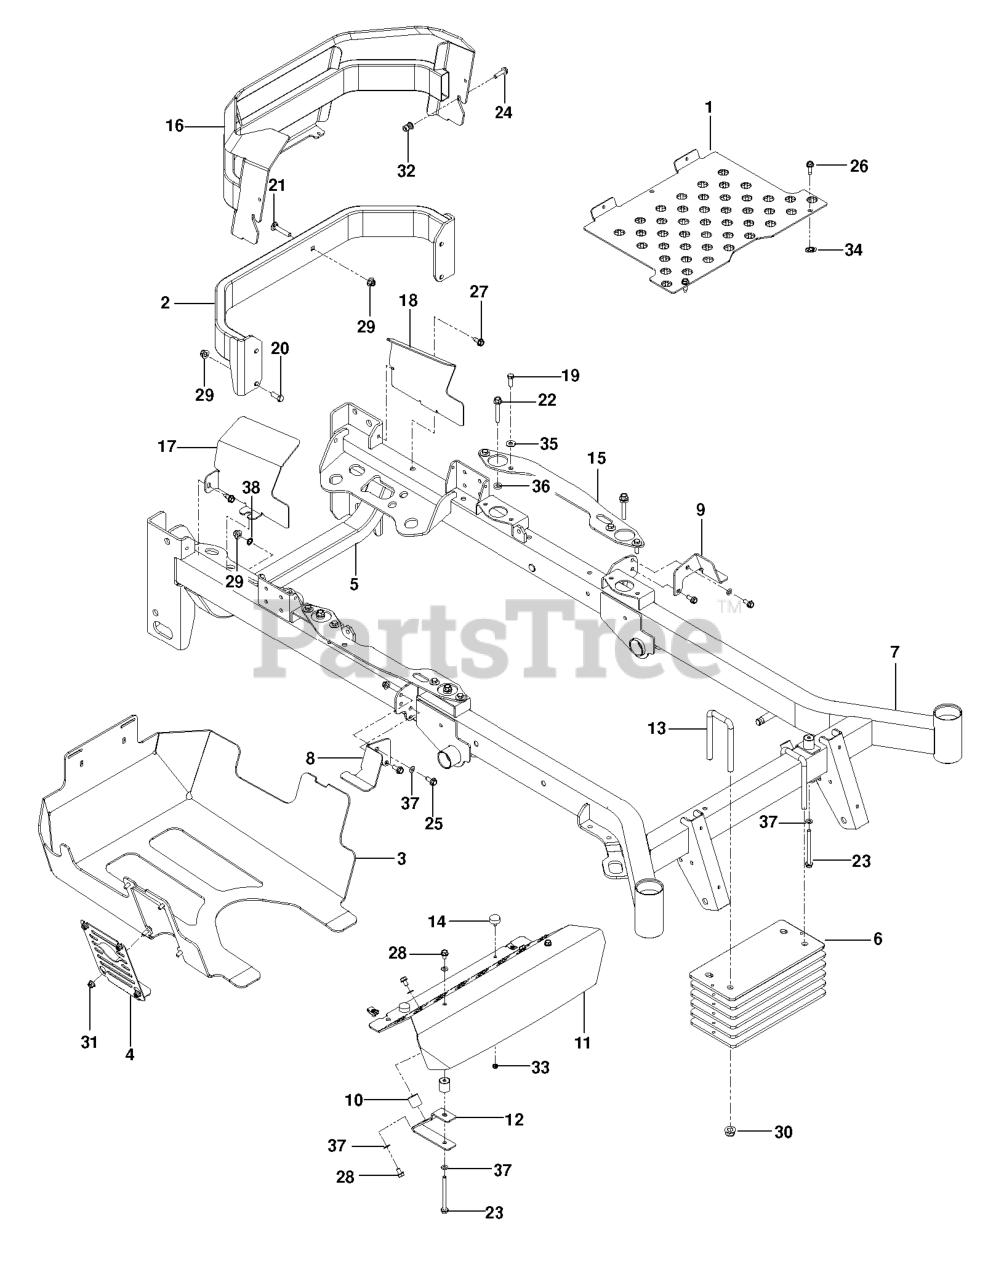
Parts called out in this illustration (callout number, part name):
1	PLATE, FLOOR PAN, OR
2	BUMPER, REAR, ORG
3	SKID.PLATE.GRAY
4	PANEL.ACCESS.GRAY
5	CROSS MEMBER, GRAY
6	PLATE, WEIGHT BLK
7	FRAME.W/DECALS.PZ6029/PZ29
8	XX MOUNT, TANK, RT-BLK
9	MOUNT, TANK, LT-BLK
10	MOUNT, F/F INSERT
11	PLATE, FOOT REST, OR
12	BRACKET, REST MOUNT
13	LINKAGE, U-BOLT
14	GROMMET, BUMPER
15	SKIRT.RH.BLK
16	GUARD, REAR W/DECALS
18	GUARD.LT.REAR.GRAY
19	HCS 5/16C X 1
20	HCS 3/8-16X1.GRD.5.ZD
21	RHSNB 3/8C X 2
22	HHFS 3/8-16 X 2-1/4 GR 5 ZD
23	HHFS 5/16-18 X 3 3/4
24	HHFS 5/16-18 X 1.25 TPBLT GD 5
25	HHFS 5/16-18 X 3/4
26	RP BLT 5/16-18 X 1 THRD FORM D
27	BOLT 5/16-18 X 3/4
28	SCR 5/16-18 X 1/2 SELFTAP ZN
29	NUT 3/8-16 HEX FLG NYLOC ZD
30	NUT, 1/2-13 HEX FLG NYLOC ZD
31	5/16-18 NYLOC FLANGE NUT
32	NUTSERT 5/16-18 THICK GRIP
33	JAM NUT 1/4C (2 2 PW01)
34	WASHER 5/16"
35	WASHER 5/16 FLAT
36	WASHER 3/8 X 3/4 X .187 TK
37	WASH 5/16 DISC SPRING ZD
38	WASHER 3/8 EXT STAR ZD
